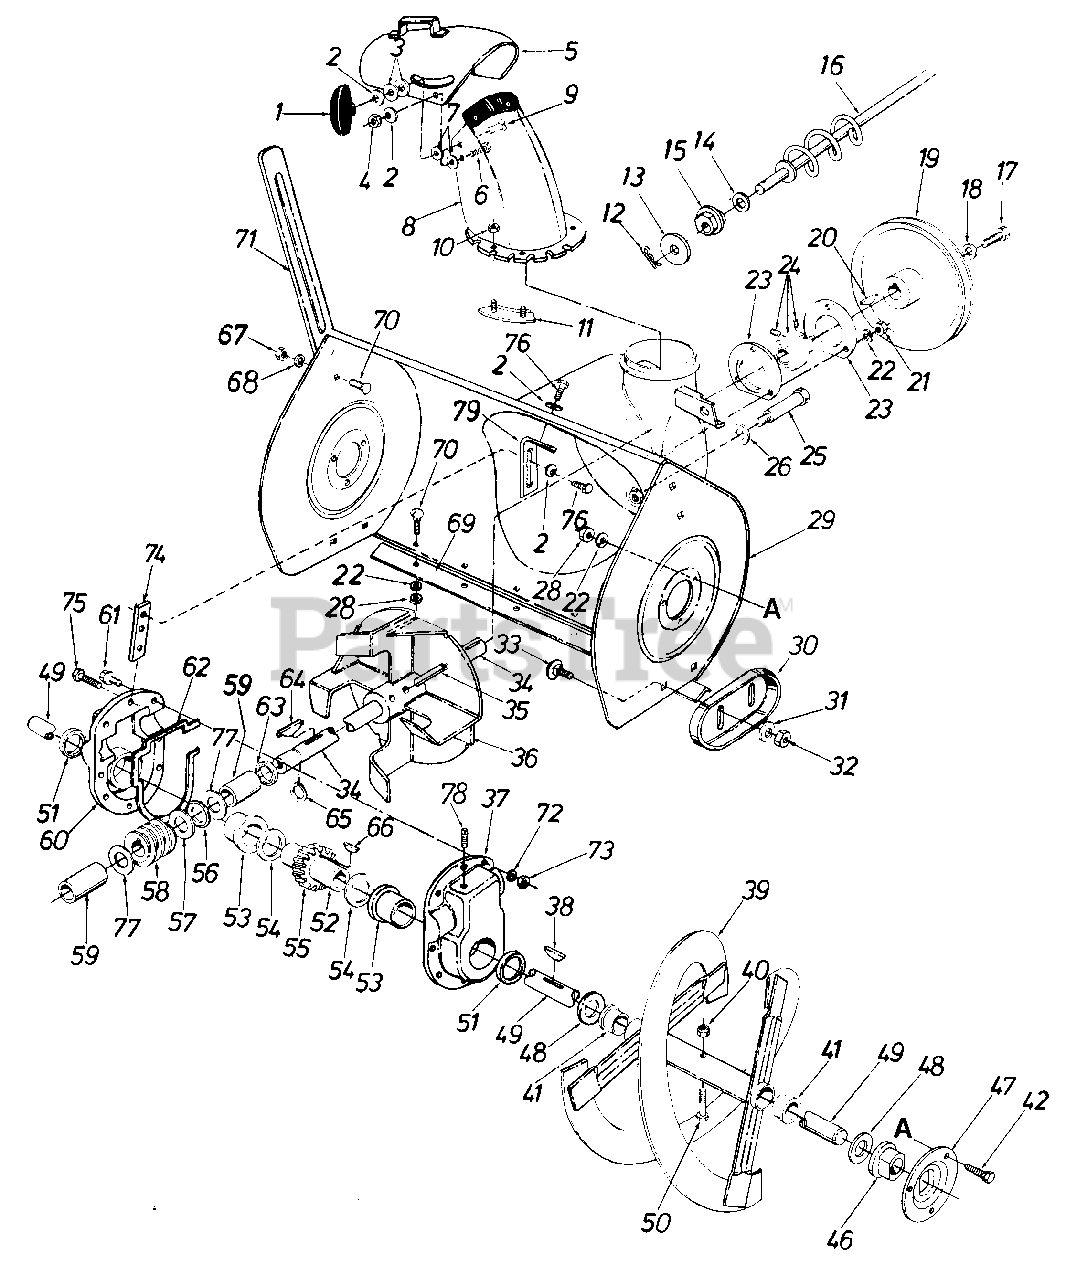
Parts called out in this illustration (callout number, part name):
1	Hand Knob Ass'y.
2	Bell-Wash. .345 I.D. x.88 O.D. x .060
3	Fl. Wash. .312 I.D. x 1.125 O.D. x .125
4	Hex Cent. L-Nut 5/16-18 Thd.
5	Top Chute Ass'y.
6	Carr. Bolt 5/16-18 x .62" Lg.
7	Fl-Wash. .53 I.D. x 1.25 O.D. x .100
8	Chute Ass'y.
9	Carr Bolt 5/16-18 x 1.00" Lg.
10	Hex Cent. L-Nut 1/2-20 Thd.
11	Chute Flange Keeper Ass'y.
12	Cotter Pin
13	Fl-Wash. .390" I.D. x 1.50" O.D.
14	Fl-Wash. .385" I.D. x .62" O.D.
15	Hex Bushing
16	Chute Crank Ass'y.
17	Hex L-Scr. 5/16-18 x .88" Lg.
18	Bell-Wash. .345 I.D. x .88 O.D. x .060
19	V-Pulley .875 I.D. x 10.12 O.D.
20	#9 Hi-Pro Key 3/16 x 3/4" Dia.
21	Hex Nut 5/16-18 Thd.*
22	L-Wash. 5/16" Scr.*
23	Bearing Hsg.-Self Aligning Brg.
24	Self Aligning Brg. .875 I.D.
25	Stud 3/8-16 x 2.75" Lg.
26	Bell-Wash. .400 I.D. x .88 O.D. x .060
28	Hex Nut 5/16-18 Thd.*
29	Blower Hsg. Ass'y.
30	Slide Shoe
31	Bell-Wash. .400 I.D. x .88 O.D. x .060
32	Hex Jam Nut 3/8-16 Thd.
33	Carr. Bolt 3/8-16 x .62" Lg.
34	Blower Axle
35	Spring Pin Spiral 5116" Dia. x 1.75" Lg.
38	#91 Woodruff Key 1/4" x 3/4" Dia.
41	Plastic Bushing
42	Hex Sems Scr. 5/16-18 x .75" Lg.*
46	Flange Brg. wlFlats 1.0" I.D.
47	Bearing Hsg.-Spiral Hsg.
48	Fl-Wash. 1.06 I.D. x 1.75" O.D. x .100
49	Spiral Axle-26"
50	Hex Bolt 5/16-18 x 1.75" Lg.
51	Oil Seal 1.50" I.D.
52	Worm Gear Shaft
53	Flange Brg. 1.503 I.D.
54	Fl-Wash. 1.50 I.D. x 2.00 O.D. x .030
55	Double Threaded Worm Gear
56	Thrust Brg. .88 I.D. x 1.44 O.D. x .078
57	Fl-Wash. .88 I.D. x 1.40 O.D. x .150
58	Double Threaded Worm- L. H .
59	Sleeve Brg. .875 I.D.
60	Complete Gear Hsg. Half- R.H. (Incl. Ref. Nos. 51 & 53)
61	Hex Scr. 5/16-18 x 1.00" Lg.
62	Gasket
63	Oil Seal .875" I.D.
64	#9 Hi-Pro Key 3/16 x 3/4" Dia.
65	Snap Ring for .875" Dia. Shaft
66	#91 Woodruff Key 1/4 X .3/4" Dia.
72	Wave Wash. 5/16" Scr.*
73	Hex Ins. L-Nut 5/16-18 Thd.
74	Gear Hsg. Support Plate
75	Hex Scr. 5/16-18 x 1.25" Lg.
76	Hex Wash. Hd. Self-Tap Scr. 5/16-18 x .75" Lg.
77	Fl-Wash. .88 I.D. x 1.40 O.D. x .150
78	Filler Plug
